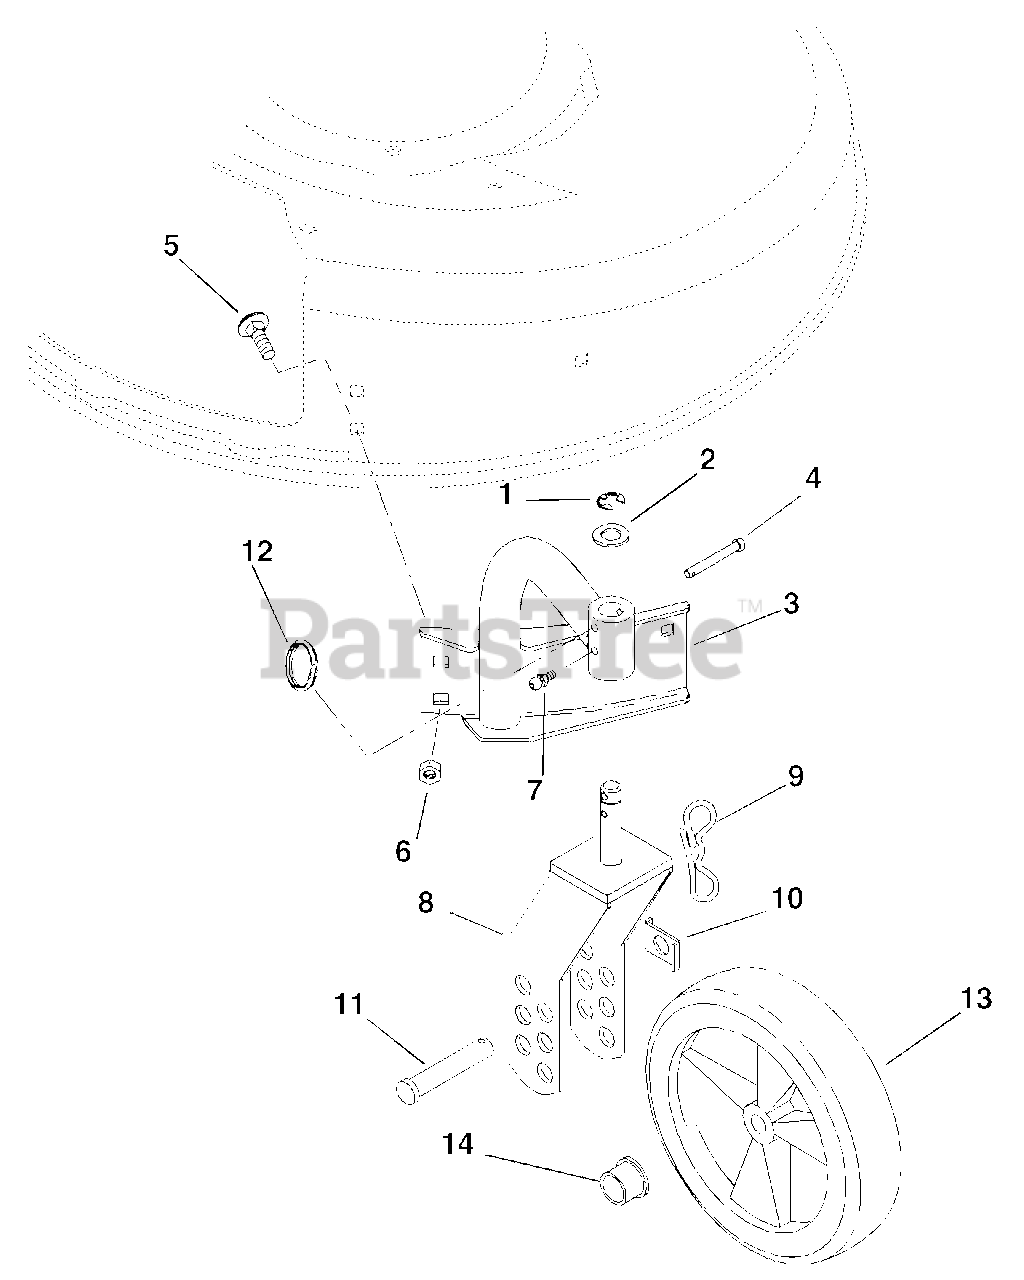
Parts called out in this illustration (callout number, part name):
1	RG-RTNG-EXT .625X.042
2	WSHR-FL-STL .630X1.005X.062 YZ
3	MOUNT, W/BSHG RIGHT ARM
4	PIN-CLEV .25X1.75 YWZC
5	@BLT-RDHDSQNK .31-18X.50 G5YZ
6	@NUT-SPNLK-FLG .312-18 YWZC
7	FTG-LUBE .25-28X.256 YWZC
8	WHEEL YOKE WELDMENT
9	PIN, BOWTIE COTTER
10	AXLE TAB
11	PIN-CLEV .494X2.62 YWZC
12	KICKOUT RING YWZC
13	WHL 7.50" .50 BORE, 1.50 HUB
14	BSHG-FLG .500X.625X.500X.750
